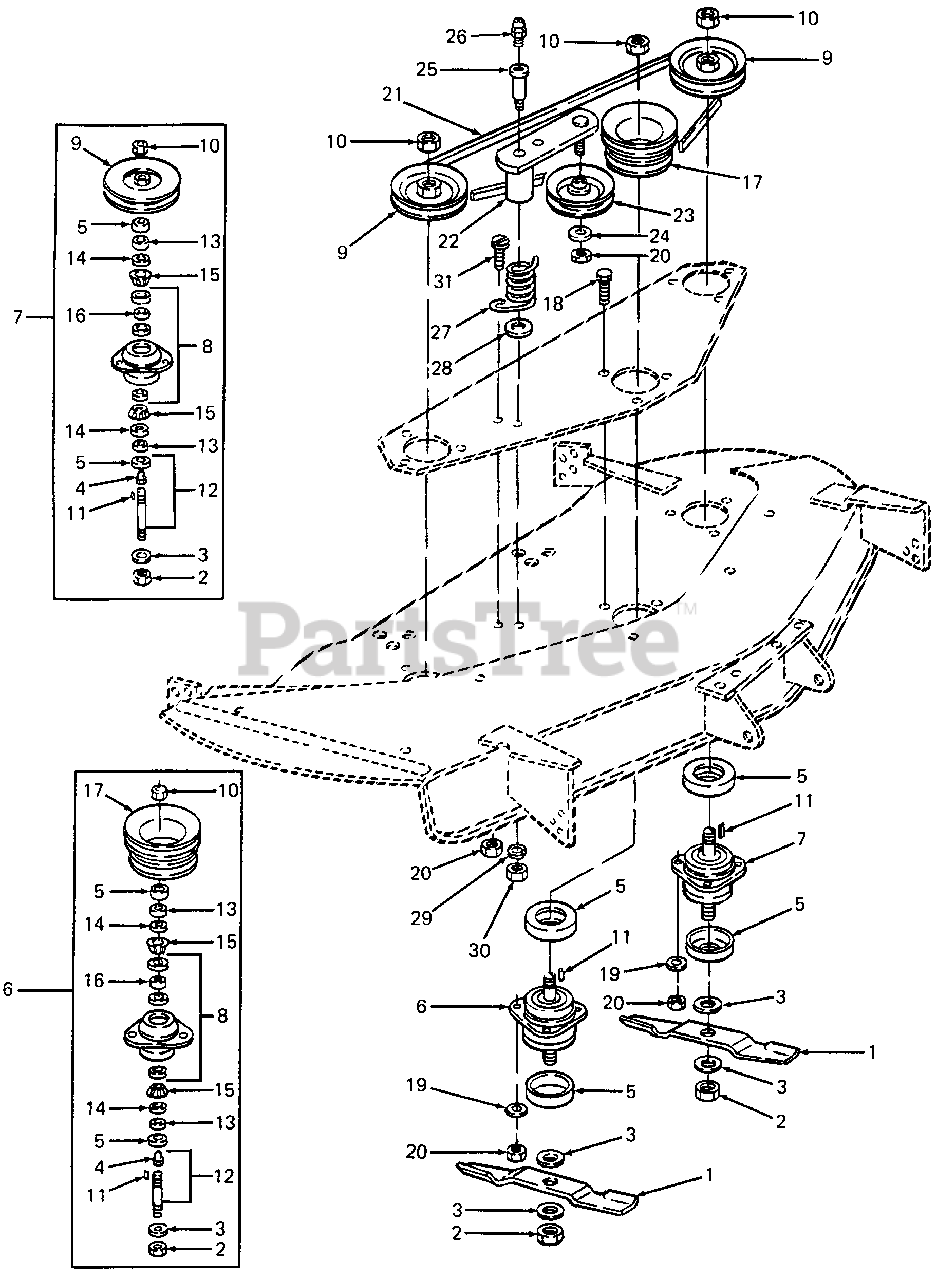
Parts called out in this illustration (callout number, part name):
2	Nut, Hex, 3/4-16 GR8
3	Washer, Flat, .781 X 2.0 X .105 - Hdn
4	Fitting, Lube, 3/16
5	Cup, Spindle (HDN)
6	Spindle Service Kit - Center
7	Spindle Service Kit - Outside
8	Housing, Spindle w/Cups
9	4L V-Pulley, 4.62 OD X .75 ID
10	Nut, Hex Jam, 3/4-16
11	Key, #91 Woodruff, 1/4 X 3/4 - Hdn
12	Kit, Shaft w/Seal
13	Spacer, .755 X 1.25 X .44 Lg
14	Seal, Oil, 1.25 X 1.874 X .25
15	Cone, Bearing
16	Spacer, Bearing
17	Pulley, Double
18	Screw, Hex Cap, 3/8-16 X 1.0 Lg GR5
19	Washer, Flat, .378 X 1.0 X .127 Thk
20	Nut, Hex Flanged Lock
21	Belt, Spindle Drive
22	Arm Assy, Idler
23	Pulley, Flat Idler
24	Washer, Flat, .406 X .75 X .063 Thk
25	Bolt, Shoulder
26	Fitting, Lube, 3/16 Drive
27	Spring, Torsion
28	Washer, Flat, .469 X .875 X .105 Thk
29	Washer, Lock, 7/16
30	Nut, Hex, 7/16-14 GR5
31	Screw, Truss Hd, 3/8-16 X .75 Lg
